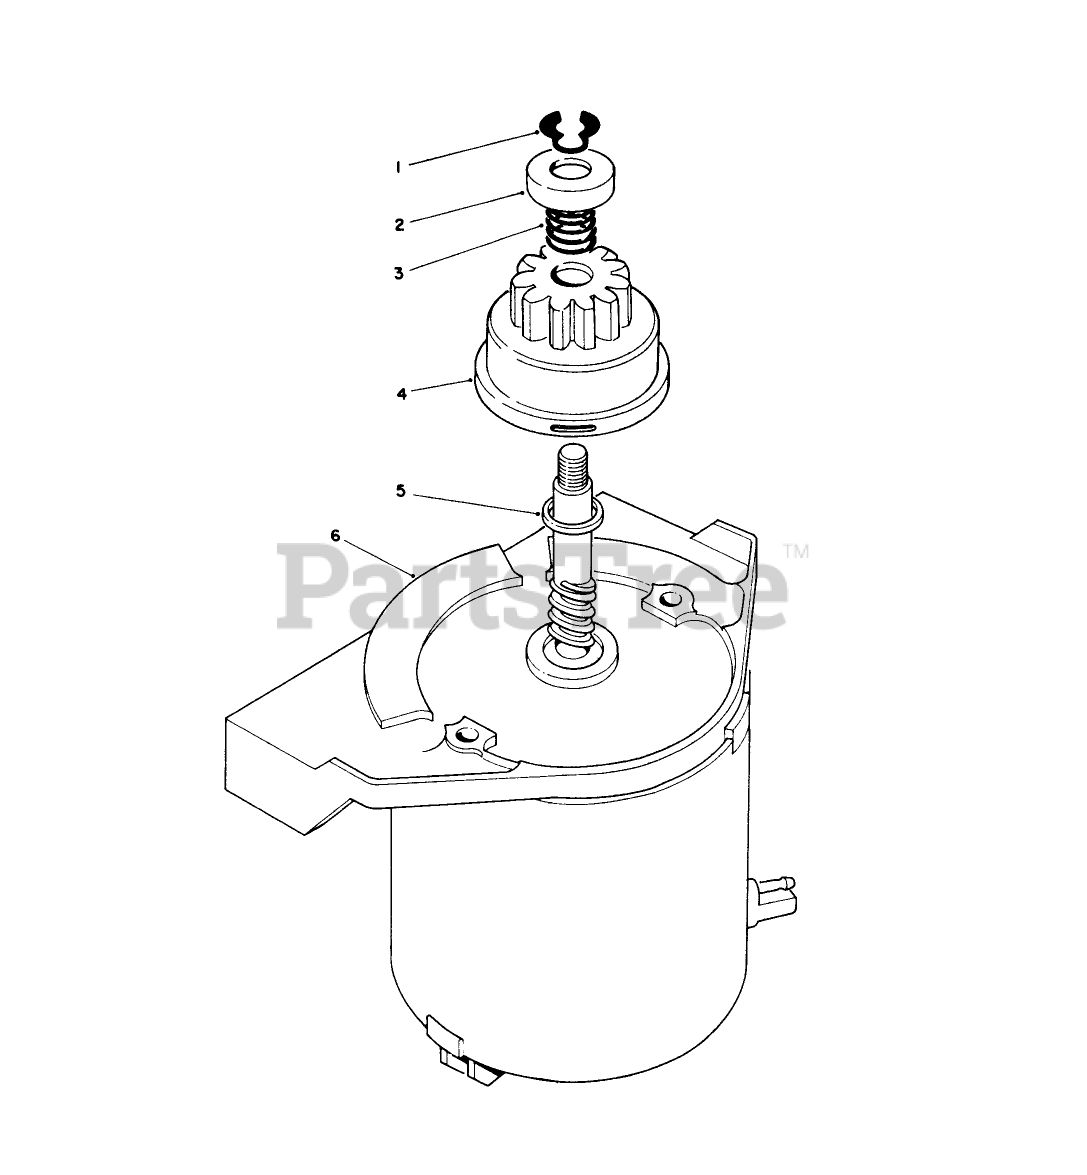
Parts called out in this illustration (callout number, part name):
1	RING-RETAINING
2	PINION STOP
3	COMPRESSION SPRING
4	PINION ASM
5	SPACER
6	END FRAME ASSY, MOTOR
